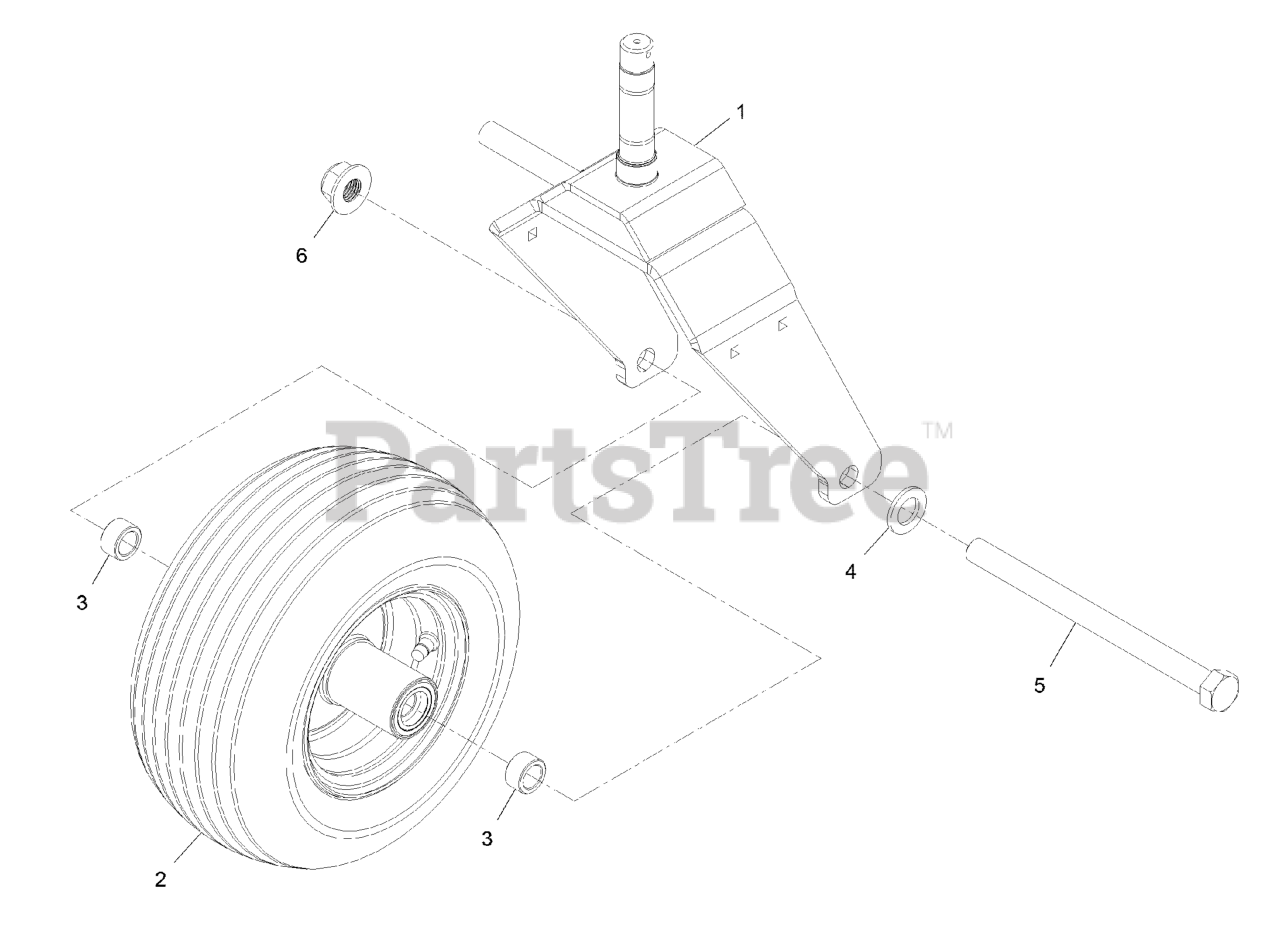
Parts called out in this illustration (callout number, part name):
1	Fork-Caster, LH [red]
2	WHEEL AND TIRE
3	SPACER-AXLE
5	SCREW-HH
